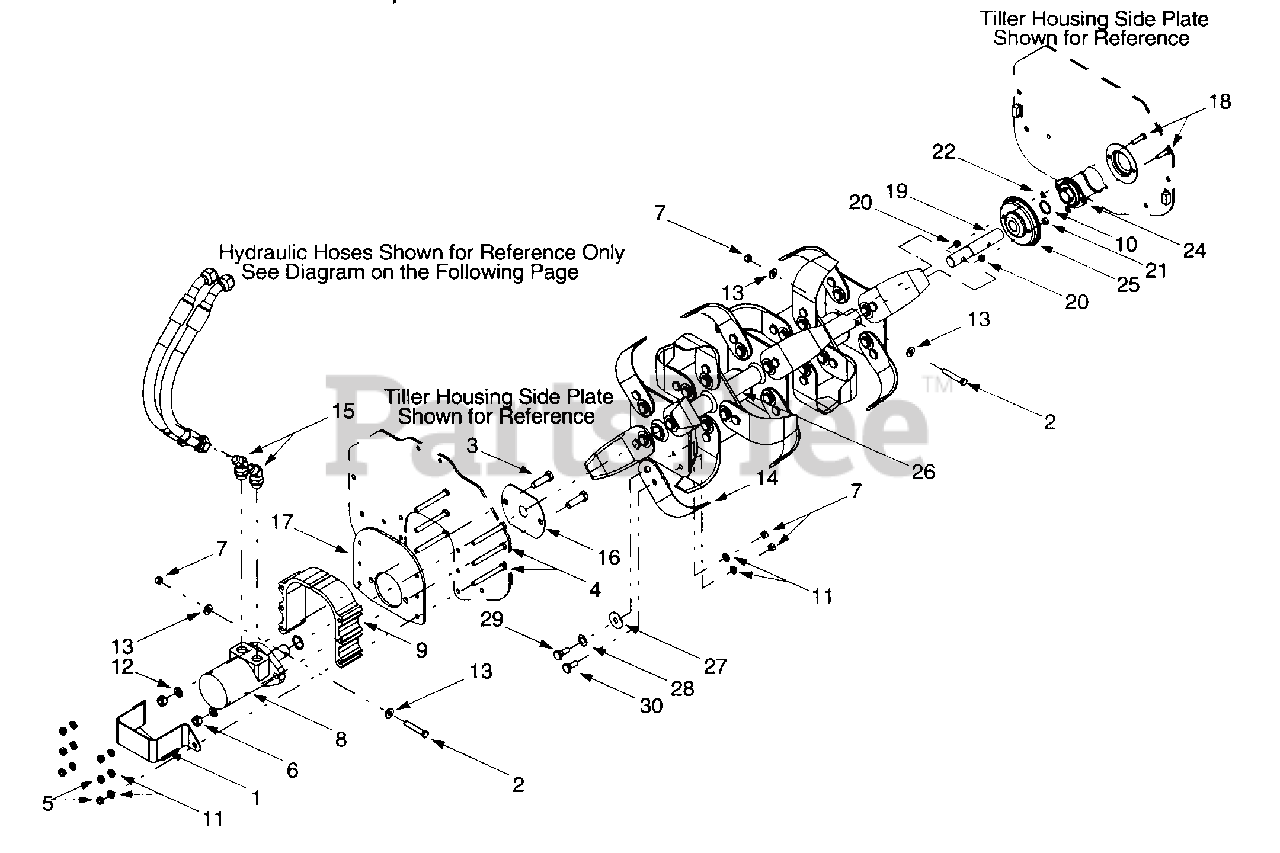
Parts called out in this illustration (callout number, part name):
1	Hydraulic Motor Guard
2	Hex Cap Screw, 3/8-24 x 2.25
3	Hex Cap Screw, 1/2-13 x 1.75
4	Hex Cap Screw, 3/8-16 x 3.5
5	Hex Lock Nut, 3/8-16
6	Hex Lock Nut, 1/2-13
7	Hex Lock Nut, 3/8-24
8	Eaton Hydraulic Motor
9	Hydraulic Motor Mounting Spacer
10	O Ring Seal
11	Lock Washer, 3/8
12	Lock Washer, 1/2
13	Flat Washer, .406 x.875 x.105
14	Articulating Tine
15	45° Hydraulic Adapter, 7/8
16	Hydraulic Motor Cover
17	Hydraulic Motor Mounting Plate
18	Hex Cap Screw, 5/16-18 x 1.25
19	Tine Shaft
20	Hex Lock Nut, 5/16-18
21	Hex Nut, 5/16-18
22	Lock Washer, 5/16
23	Flange Bearing, 1.0
24	Dust Cap Cover
25	Bearing Cover
26	Tine Adapter Assembly
27	Flat Washer, .51 x 1.5 x .07
28	Belleville Washer
29	Shoulder Screw, .49 x .21, 3/8-24
30	Shoulder Screw, .49 x .34, 3/8-24
